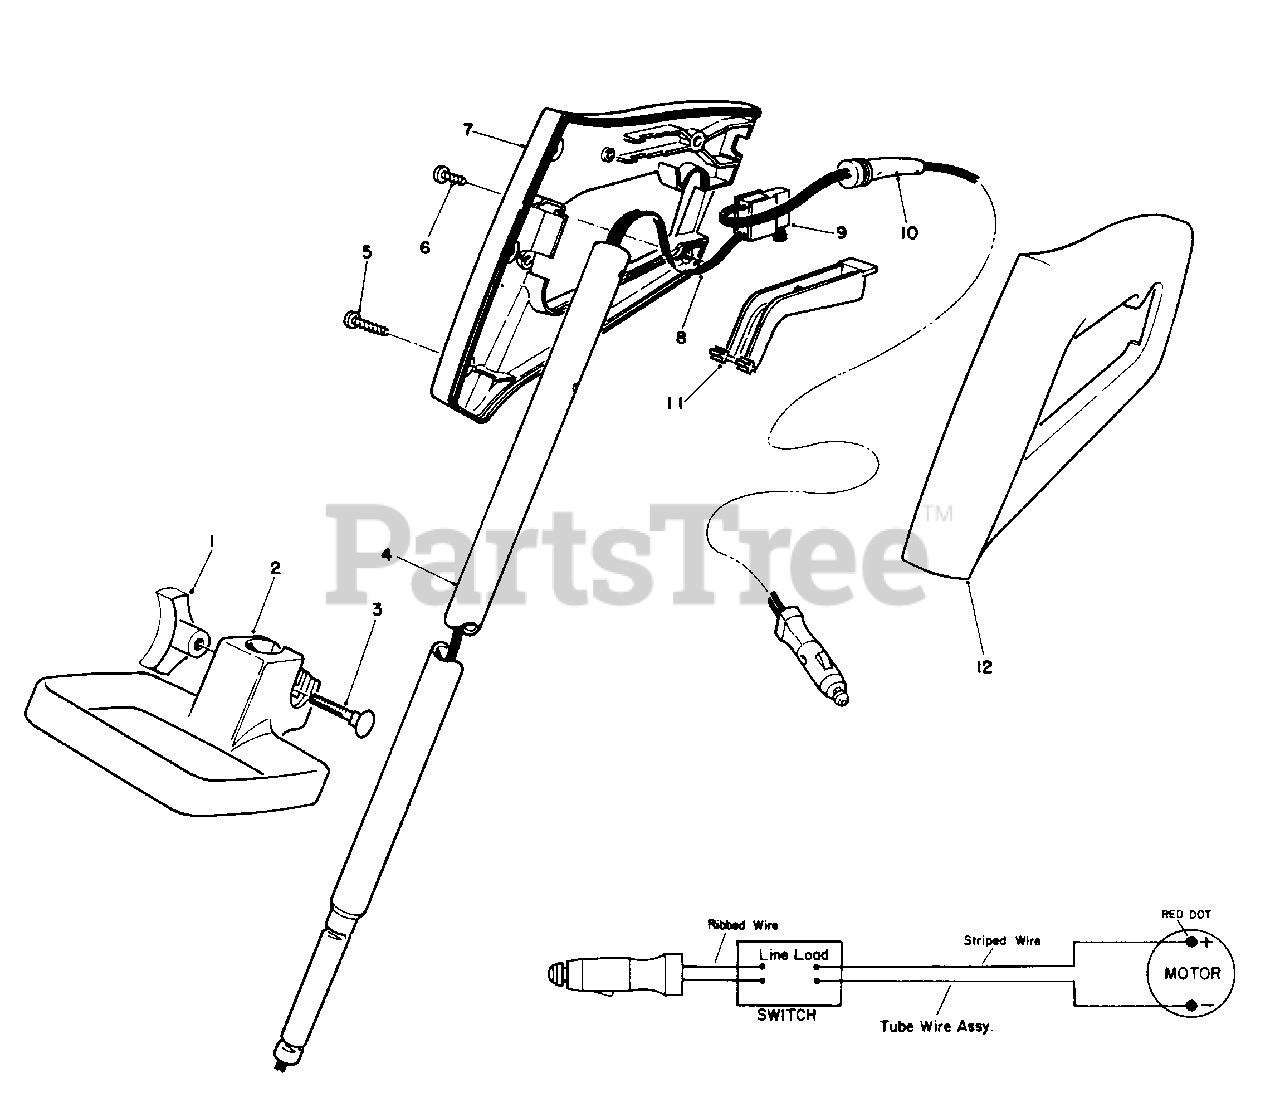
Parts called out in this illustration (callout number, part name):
1	Knob-Adjust
2	Handle-Adjust
3	Bolt-Carriage
4	Tube-Handle
5	Screw-Thread Forming
6	Screw-Thread Forming
7	Grip-Handle, R.H. Wire
8	Assembly-Tube
10	Cord Assembly-Tube
11	Bar-Switch
12	Grip-Handle, L.H.
